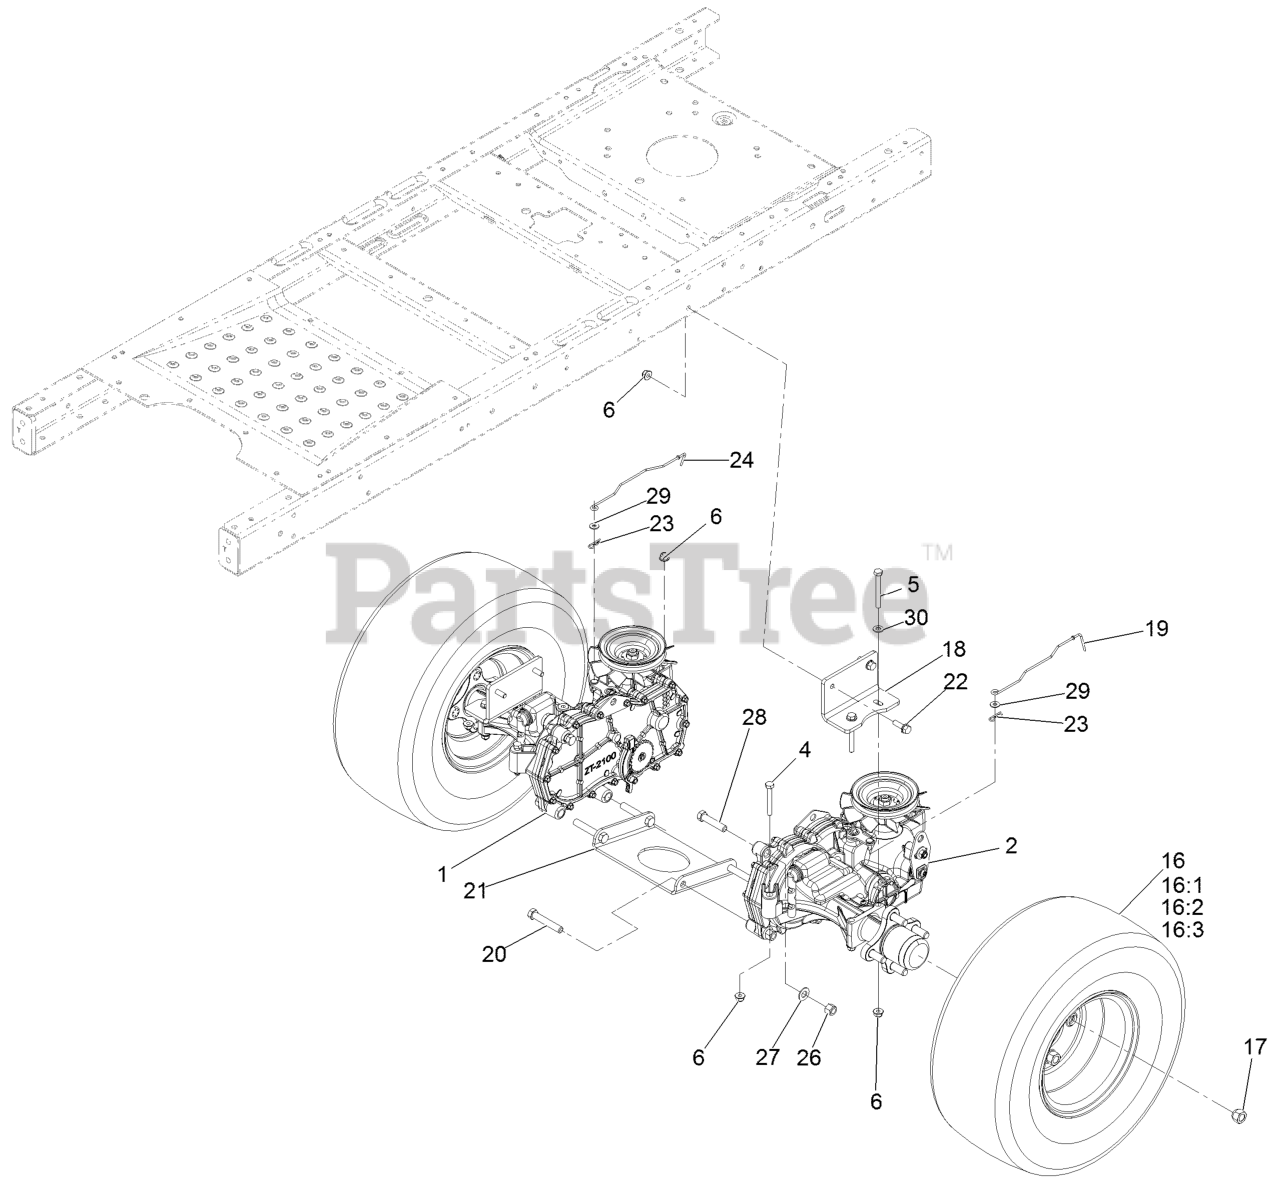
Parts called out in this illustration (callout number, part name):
1	RH HYDRO TRANSAXLE ASM
2	LH HYDRO TRANSAXLE ASM
4	SCREW-HH
5	SCREW-HH
6	NUT-HF, NI
16	2 PLY WHEEL AND TIRE ASM
16:1	TIRE-2 PLY
16:3	Stem-Valve
16:99	TUBE-TIRE
17	NUT-LUG
18	MOUNT-HYDRO
19	ROD-BYPASS, LH
20	SCREW-HH
21	PLATE-CROSS, HYDRO
22	SCREW-HHF
24	ROD-BYPASS, RH
26	NUT-LOCK, NI
27	WASHER-FLAT
28	SCREW-HH
30	WASHER-PLAIN
